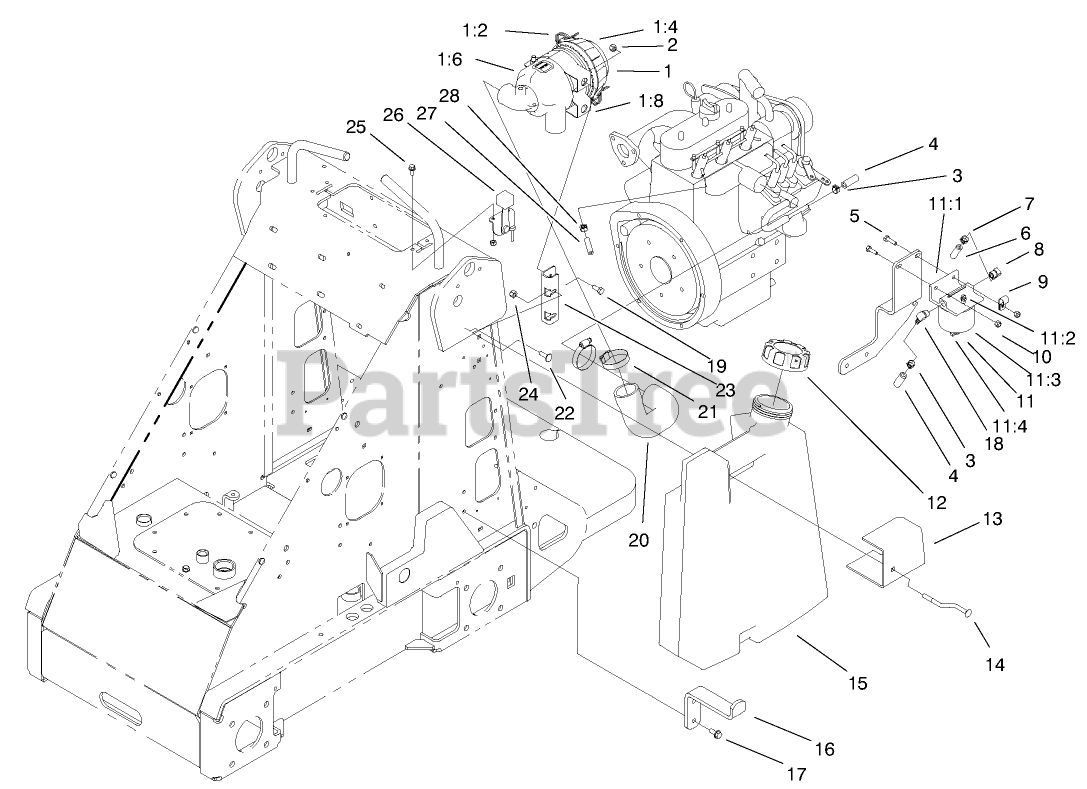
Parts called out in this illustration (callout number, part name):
1	AIR CLEANER ASM
1:2	CLIP-CLEANER, AIR
1:4	COVER
1:6	HOUSING
1:8	MOUNTING BRACKET ASM
2	NUT-LOCK, NI
3	CLAMP-HOSE
4	HOSE-FUEL
5	SCREW-HH
6	HOSE-FUEL
7	CLAMP-HOSE
8	ELBOW
9	CLAMP-R
10	NUT-LOCK, NI
11	SEPARATOR-FILTER / WATER
11:1	HEAD ASM
11:2	VENT-AIR
11:3	ELEMENT-SPIN ON
11:4	VALVE-DRAIN
12	DIESEL FUEL CAP ASM
13	PLATE-MOUNT, LEFT
14	BOLT-MOUNT
15	Fuel Tank ASM
16	MOUNT-BOTTOM, TANK
17	SCREW-HWHTF
18	FITTING-ELBOW
19	SCREW-HH
20	HOSE-CLEANER, AIR
21	CLAMP-HOSE
22	BOLT-CARR
23	MOUNT-CLEANER, AIR
24	NUT-HF
25	SCREW-HHF
26	CONTROL-THROTTLE
27	HOSE-LINE, FUEL
28	CLAMP-HOSE
